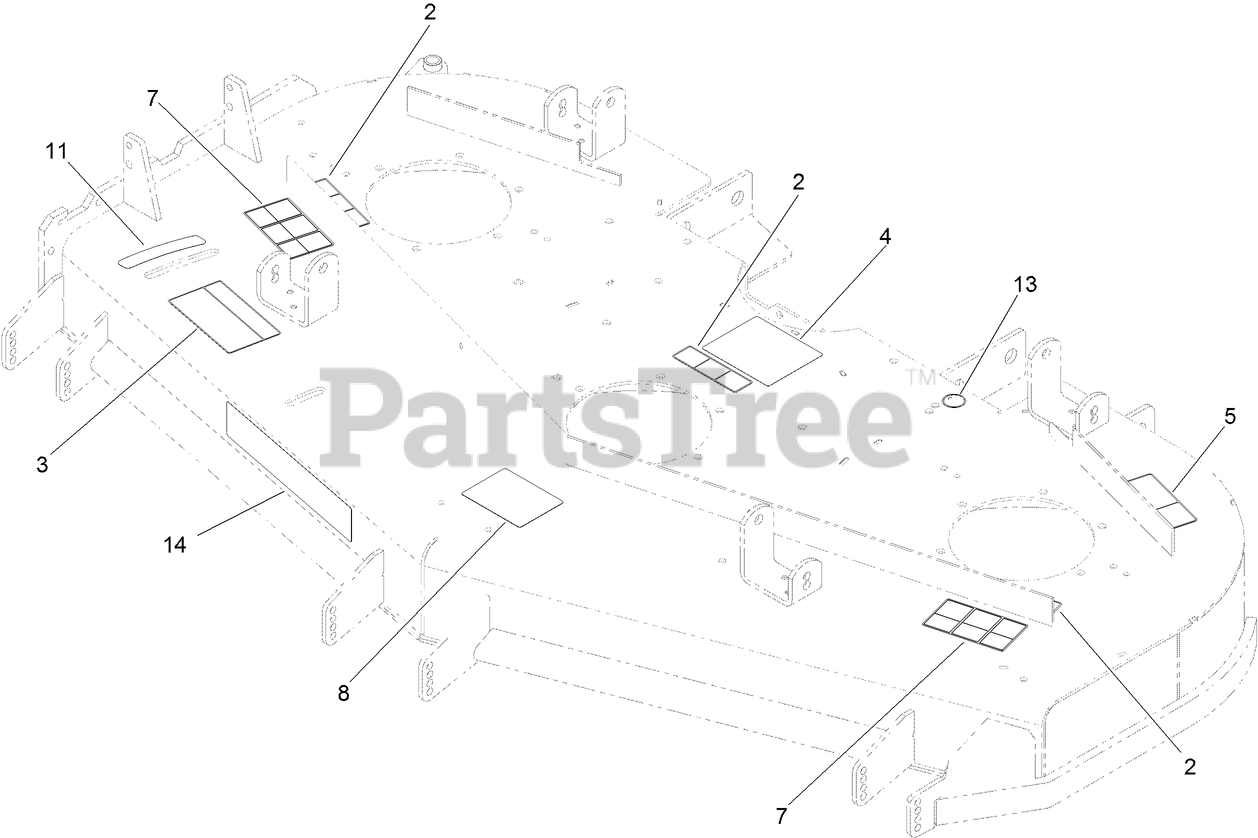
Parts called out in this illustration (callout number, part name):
2	DECAL-COVER, MISSING
3	DECAL-ADJUSTMENT, BAFFLE
4	DECAL-ROUTING, BELT
5	DECAL-TORQUE, BLADE BOLT
7	DECAL-DANGER
8	DECAL-SCALP, ANTI
11	DECAL-SETTING, BAFFLE
13	DECAL-GREASE
